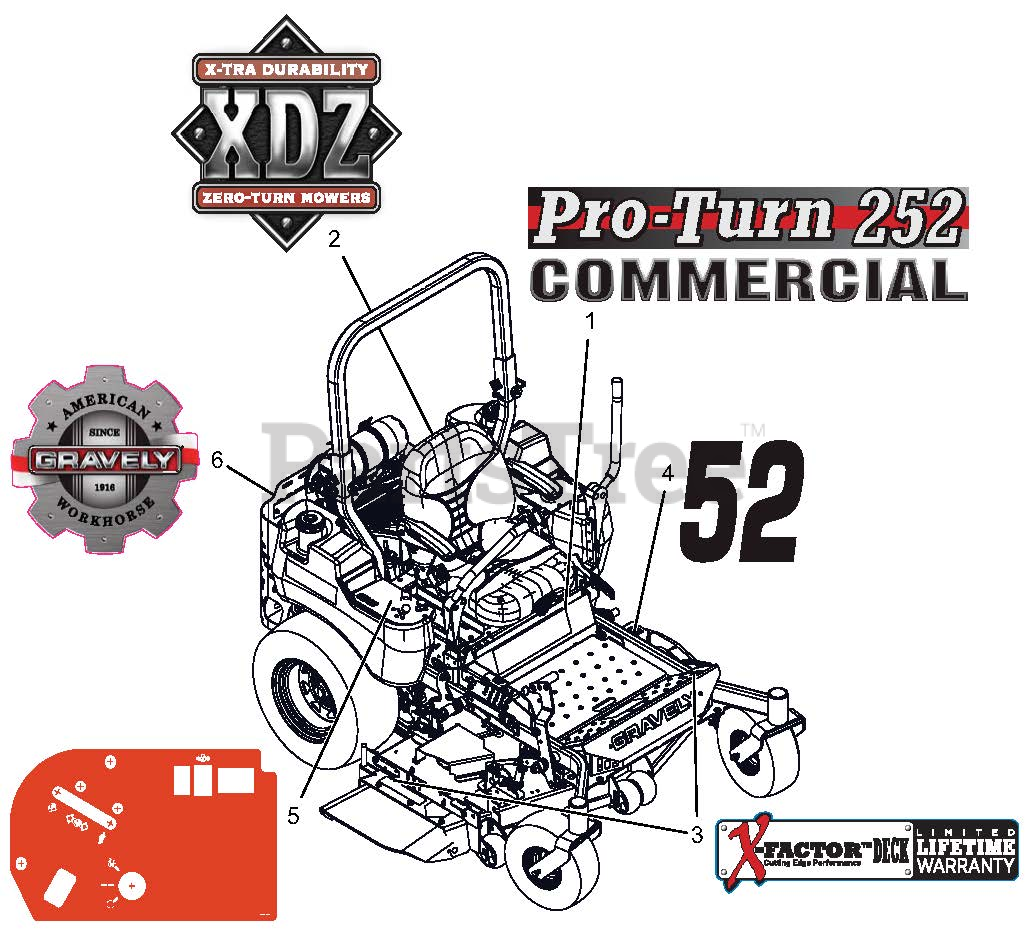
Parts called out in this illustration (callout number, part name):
1	DECAL, PROTURN 252
2	DECAL, XDZ
3	DECAL, X-FACTOR DECK
4	DECAL, 52"
5	DECAL, CONTROL PANEL EFI
6	DECAL, GRAVELY HERITAGE-LARGE
